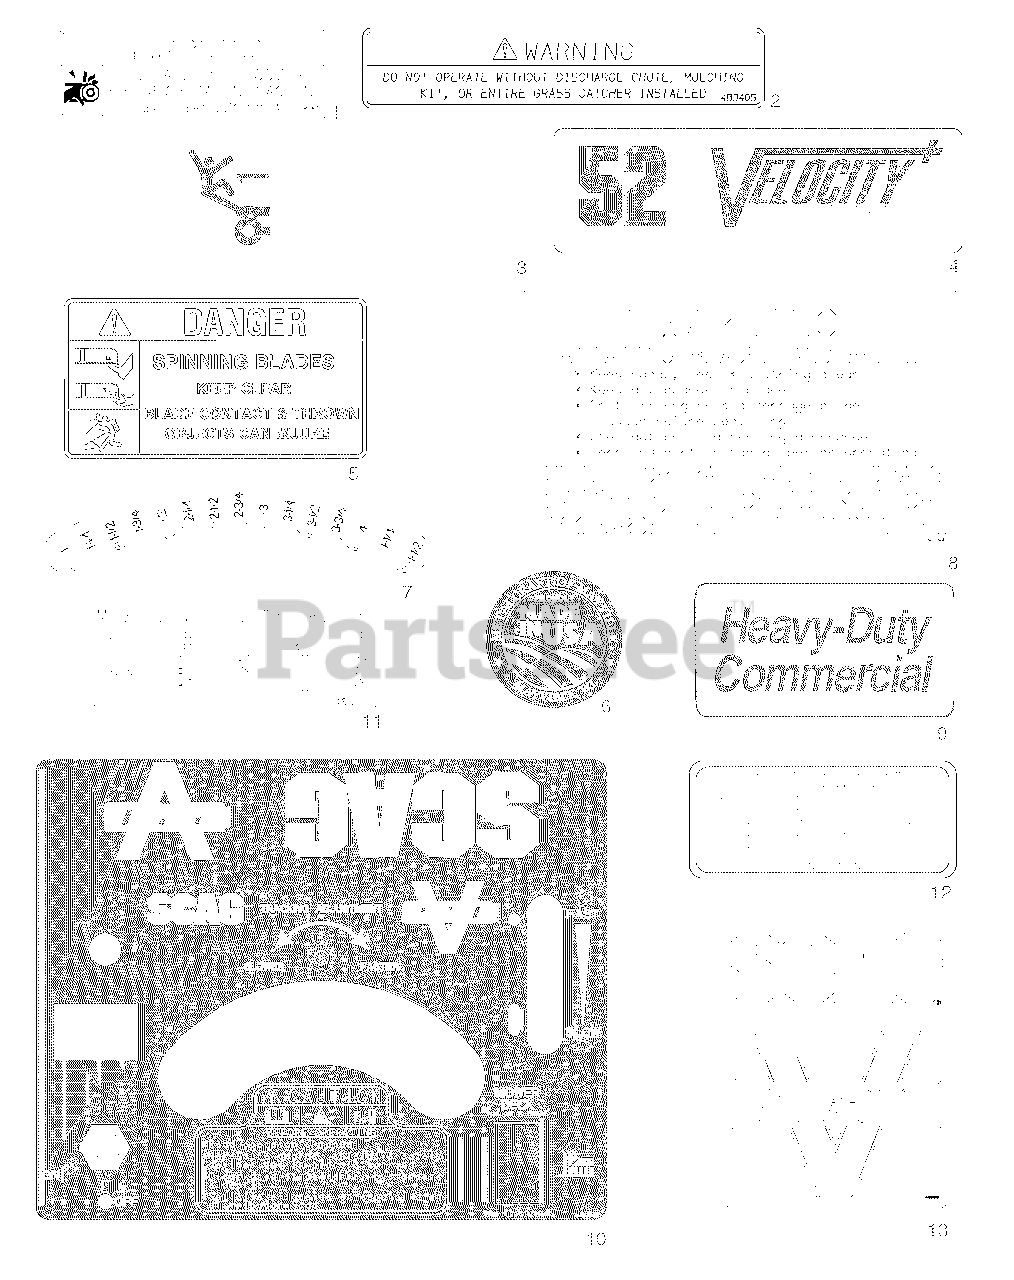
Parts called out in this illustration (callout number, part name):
1	Decal, Warning - Belt Cover
2	Decal, Warning
3	Decal, Sulky Attach
4	Decal, 52V
5	Decal, Spinning Blades
6	Decal, Metalcraft - Made in USA
7	Decal, Height-of-Cut
8	Decal, Warning - Knives
9	Decal, Heavy Duty Commercial
10	Decal, Instrument Panel
11	Decal, Module Connection
12	Decal, Patents
13	Decal, Pro-V Belt Cover
